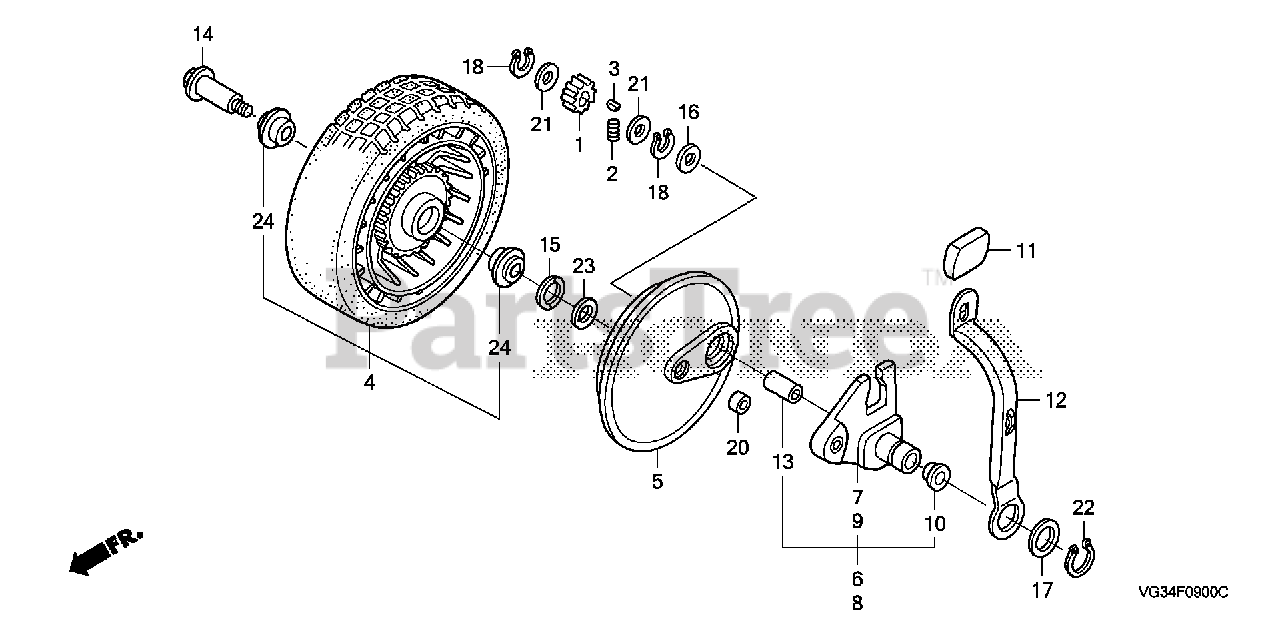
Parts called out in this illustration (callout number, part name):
1	GEAR, PINION (12T)
2	SPRING, RATCHET RETURN
3	KEY, RATCHET
4	WHEEL, RR. *NH164* (GRIP GRAY)
4	WHEEL, RR. *NH164*
6	ARM, R. RR. ADJUSTING
7	ARM, R. RR. ADJUSTER
8	ARM, L. RR. ADJUSTING
9	ARM, L. RR. ADJUSTER
10	DUST SEAL (12.7MM)
11	GRIP, ADJUSTER *NH105* (MAT BLACK)
12	PLATE, RR. ADJUSTER
13	BUSH, DRIVESHAFT
14	BOLT, RR. WHEEL SHAFT
15	WASHER, WHEEL
16	WASHER, THRUST (13MM)
17	WASHER, FLAT (26X44)
18	CIRCLIP (OUTER) (12.7MM)
20	COLLAR, THRUST
21	COLLAR, PINION GEAR
22	CIRCLIP (OUTER) (25MM)
23	WASHER, THRUST (13X27X1)
24	BEARING, WHEEL
